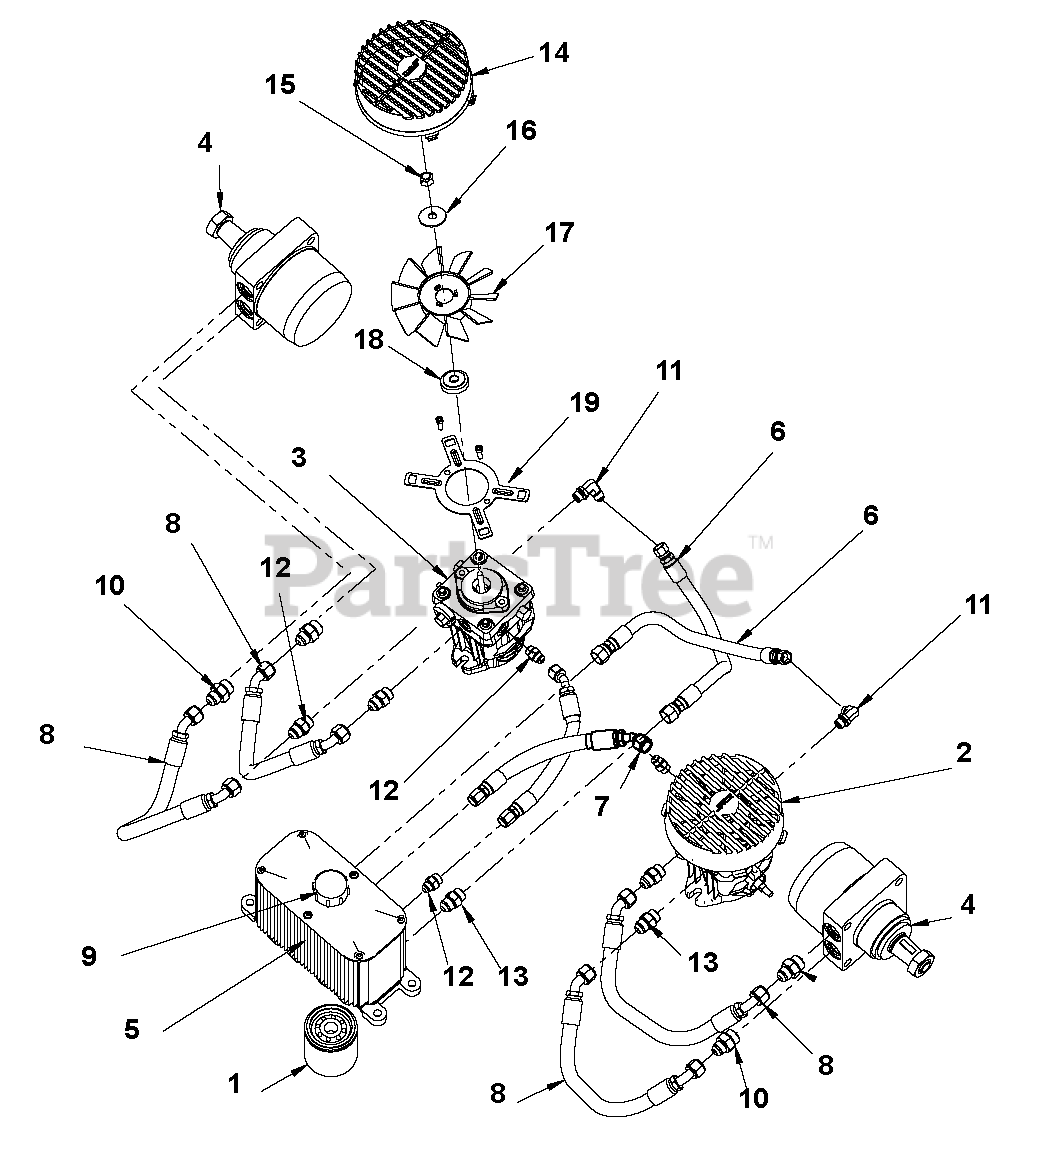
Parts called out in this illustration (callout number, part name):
1	Filter, 25 MICRON
2	Pump, Hydro-Gear Left Hand
3	Pump, Hydro-Gear Right Hand
4	Wheel Motor, Parker TL195
5	Tank, Hydraulic
6	Hose, Hydraulic 3/8 9/16 & 3/4FJICSW
7	Hose, Hydraulic 3/8 9/16JICFESW
8	Hose, Hydraulic 1/2 3/4FJICSW45°
9	Cap, Hydraulic
10	Adapter, 7/8MOR X 3/4MJIC
11	Fitting, 90 9/16 MOR X 9/16 MJIC
12	Fitting, ADP 9/16-18MORX9/16MJIC
13	Adapter, 3/4-16MORX 3/4-16JIC
14	Shroud, PUMP
15	Locknut, 3/8-24 CROWN
16	Washer, .375 X 1.24 X .072 BLVL
17	Fan,Pump
18	Hub, Fan
19	Plate, Shroud Mount
20	Seal Kit, Hydro-Gear Pump
21	Seal Kit, Parker Wheel Motor
